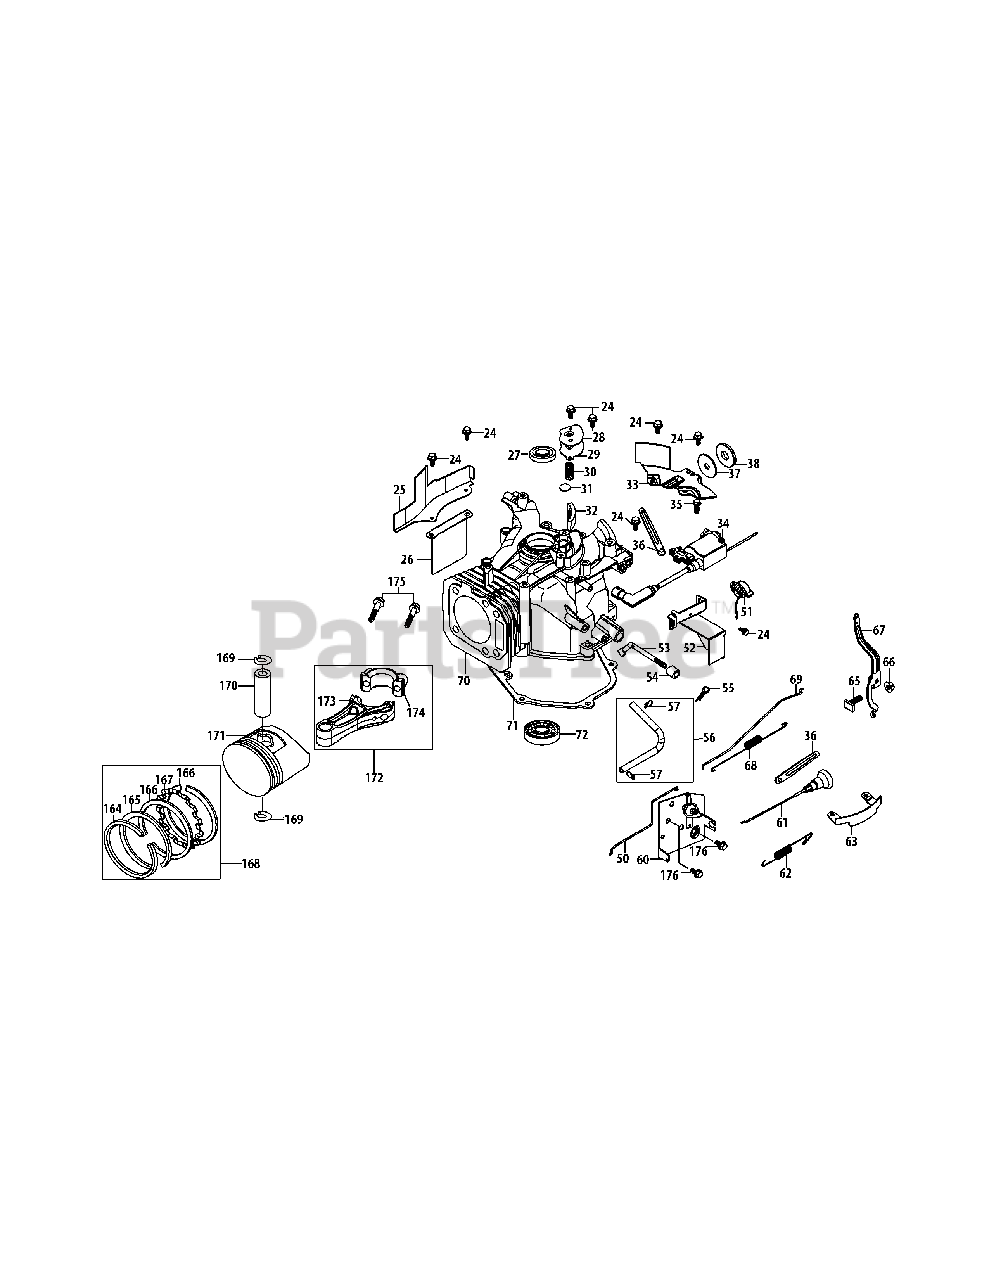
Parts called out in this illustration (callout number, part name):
24	Bolt M6×14
25	Air Guide Bracket
26	Label Bracket
27	Upper Crankshaft Seal
28	Breather Cover Plate
29	Breather Gasket
30	Breather Spring
31	Breather Valve
32	Mesh Screen
33	Fuel Tank Bottom Bracket
34	Ignition Coil Assembly
35	Bolt M6×18
36	Flexible Clamp
37	Fuel Tank Washer
38	Rubber Bushing
52	Tank Side Bracket
53	Governor Arm Shaft
54	Governor Seal
55	Cotter Pin
56	Breather Hose Assembly
57	Breather Hose Clamp
59	Choke Linkage
60	Variable Spd Control Rod Bracket
61	1P70Lh Choke Control Knob
62	Governor Spring
63	Governor Arm Shield
65	Governor Arm Bolt
66	Nut M6
67	Governor Arm
68	Throttle Rod
69	Throttle Linkage Spring
70	Shortblock Assembly
71	Crankcase Cover Gasket
72	Main Bearing
164	Upper Piston Compression Ring
165	Lower Piston Compression Ring
166	Piston Oil Ring Segment
167	Piston Oil Ring Expander
168	Piston Ring Set
169	Piston Pin Snap Ring
170	Piston Pin
172	Connecting Rod Assembly
173	Connecting Rod
174	Connecting Rod Cap
175	Connecting Rod Bolt
